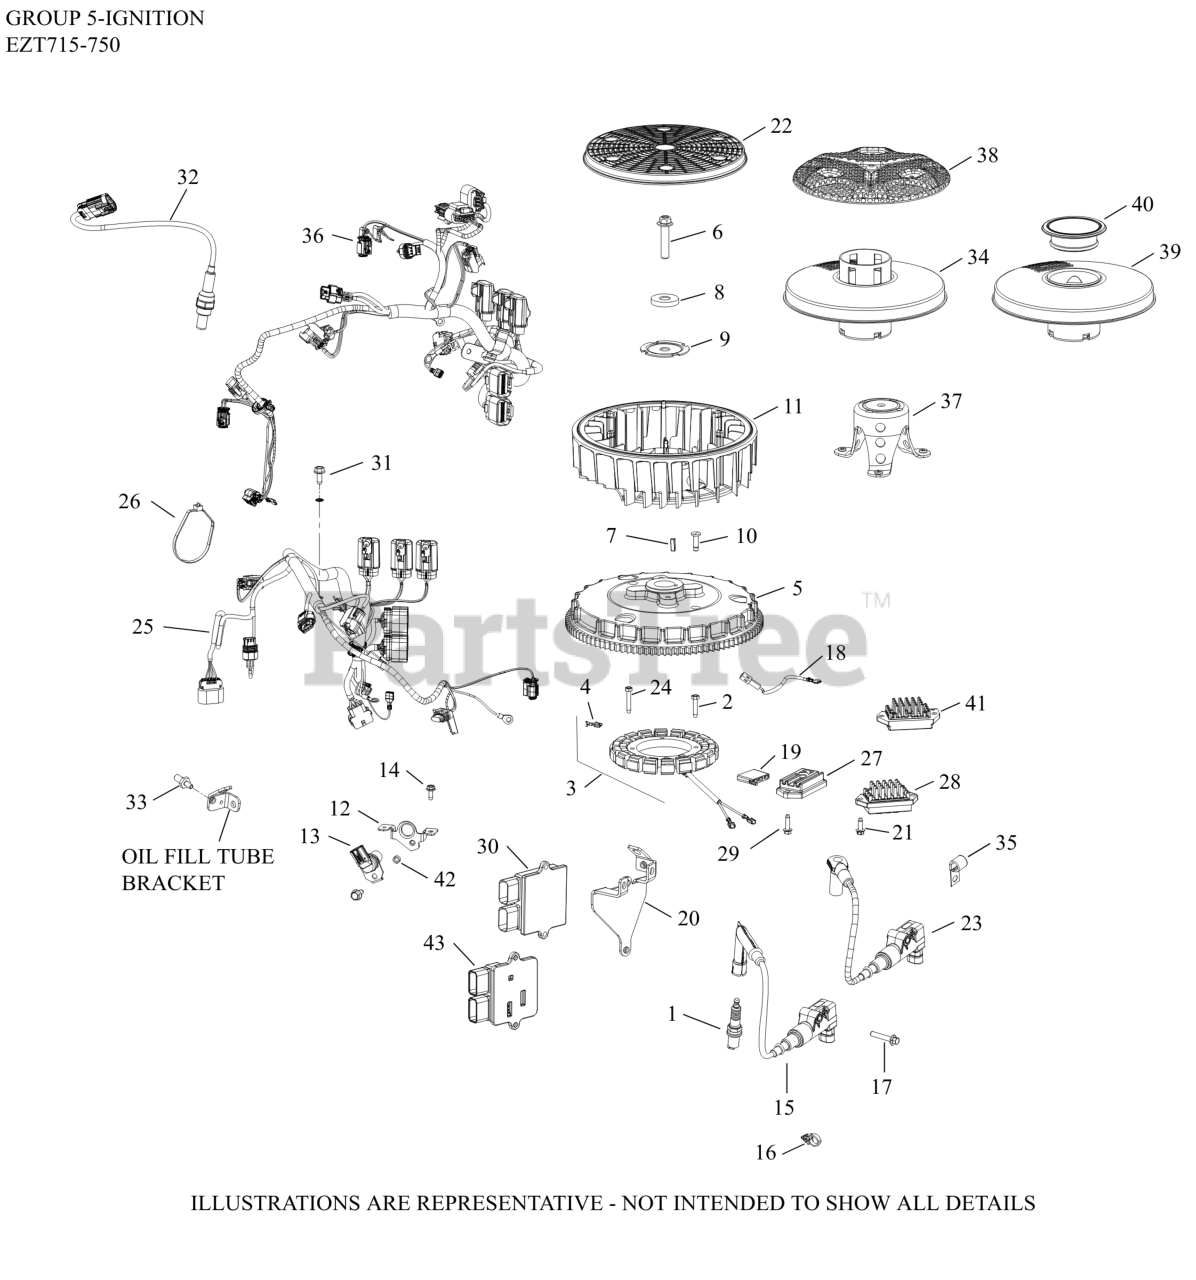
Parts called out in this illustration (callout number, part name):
1	SPARK PLUG, RFI
2	SCREW, THREAD FORMING
3	KIT, 15 / 20 AMP STATOR
5	FLYWHEEL, ASSEMBLY
6	SCREW, HEX FLANGE
7	KEY, SQUARE
8	WASHER, FLAT
9	PLATE, FAN MOUNTING
10	RETAINER, FLYWHEEL FAN
12	BRACKET, SENSOR
13	SENSOR, SPEED
14	SCREW, FLG THD FRM M5X0.8X13
16	COIL, IGNITION - EFI (RFI/EMC)
17	SCREW, FLG (BLACK) M6X1.0X34
18	LEAD, REGULATOR RECTIFIER JUMPER
19	CONNECTOR
20	BRACKET, ECU
21	SCREW, THREAD FORMING
22	SCREEN, GRASS
25	HARNESS, W/TEMP SENSOR
27	REG/RECT (15 AMP, HW, OVP)-(#2540338S)
30	MODULE, ECU
31	SCREW, CAPTIVE WASHER (SEMS)
35	CLIP, CABLE (KM)
